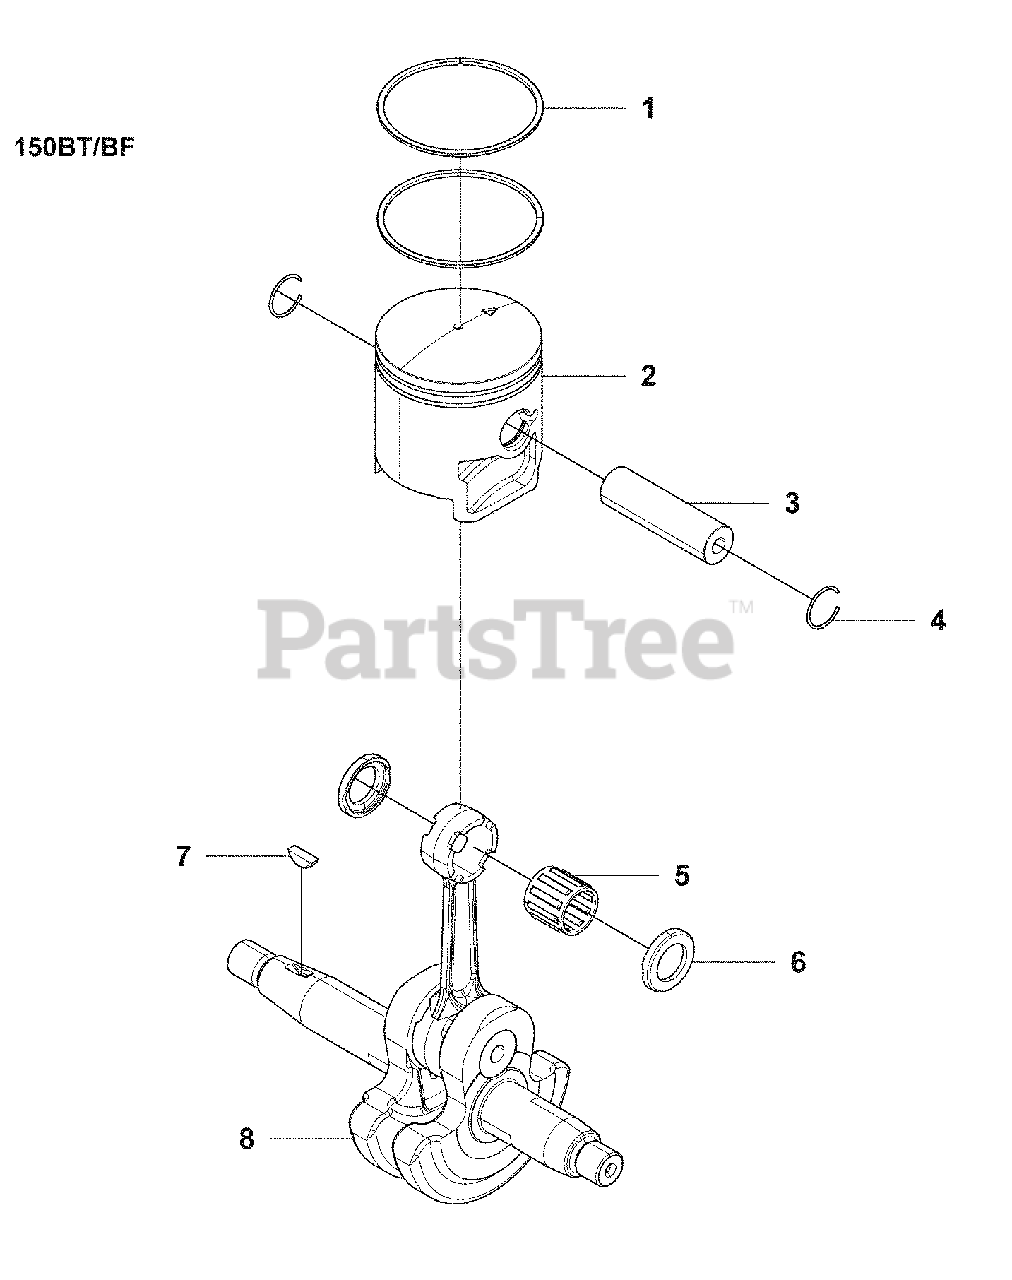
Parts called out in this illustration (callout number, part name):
1	Piston Ring
3	Piston Pin
7	Flywheel Key
8	Crankshaft
